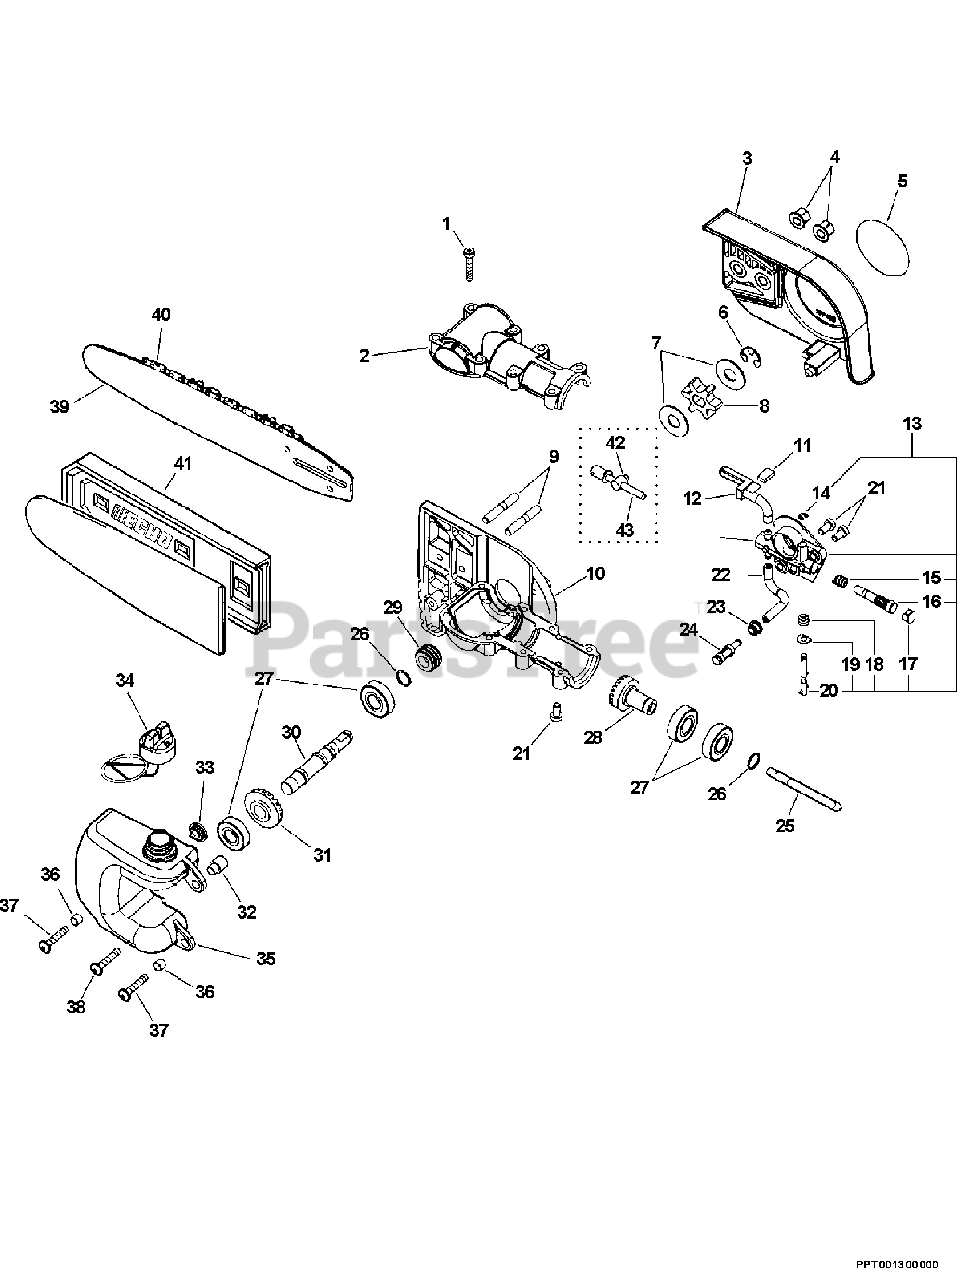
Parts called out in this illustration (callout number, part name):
1	SCREW M5×.25
2	CASE, GEAR - UPPER Ø35
3	GUARD, SPROCKET
4	NUT, FLANGE M6
5	LABEL, ECHO
6	RING, RETAINING Ø0.300
7	WASHER 10.2×24.5×1.2
8	SPROCKET, DRIVE
9	BOLT, STUD 6
10	CASE, GEAR
11	PAD, FOAM
12	PIPE, OIL OUTLET
13	AUTO-OILER ASSY
16	PLUNGER ASSY
17	CAP, OIL PUMP
20	ADJUSTER, OILER
21	SCREW M5×.8×10
22	PIPE, IMPULSE 3×6×75
23	GROMMET
24	FILTER, OIL
25	CONNECTOR, DRIVE SHAFT
26	RING, SNAP Ø12
27	BEARING, BALL
28	GEAR, BEVEL
29	GEAR, WORM
30	SHAFT, GEAR
31	GEAR, BEVEL
32	COLLAR 6
33	VENT ASSY
34	CAP ASSY, OIL
35	TANK, OIL
36	SPACER 6.2×7.8×6
37	SCREW 5×16 MM
38	SCREW 5×28
39	GUIDE BAR - 12" -- INTENZ
40	SAWING CHAIN - 91VS - 12" -- LOW PROFILE
41	SCABBARD 12"
42	TENSIONER, CHAIN
